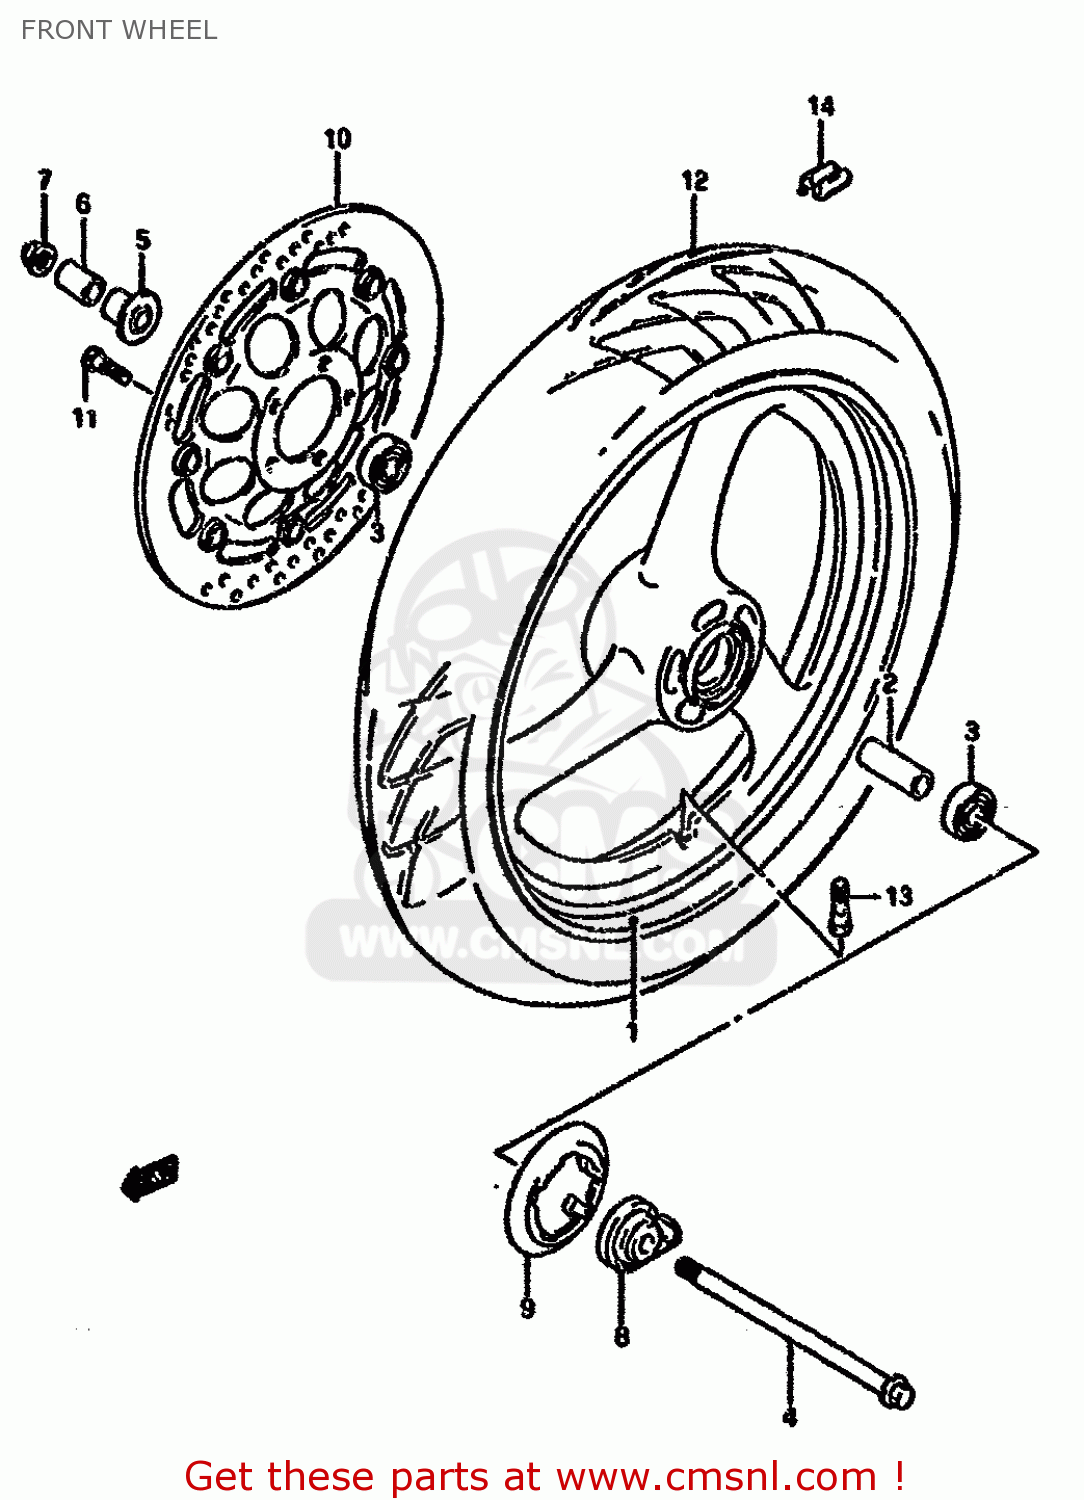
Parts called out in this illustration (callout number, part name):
1	WHEEL,FRONT (MT3.00X17)
2	SPACER(15.3X21.7X63)
3	BEARING
4	AXLE,FR
5	SPACER,FR AXLE
6	SPACER,FR AXLE,R
7	NUT
8	BOX ASSY,SPEEDOMETER GEAR
9	COVER,FR HUB,L
10	DISC,FR BRAKE,R
11	BOLT 8X33
12	TIRE,T/L(110/70-17 54H)
13	VALVE,TIRE
14	BALANCER,WHEEL
